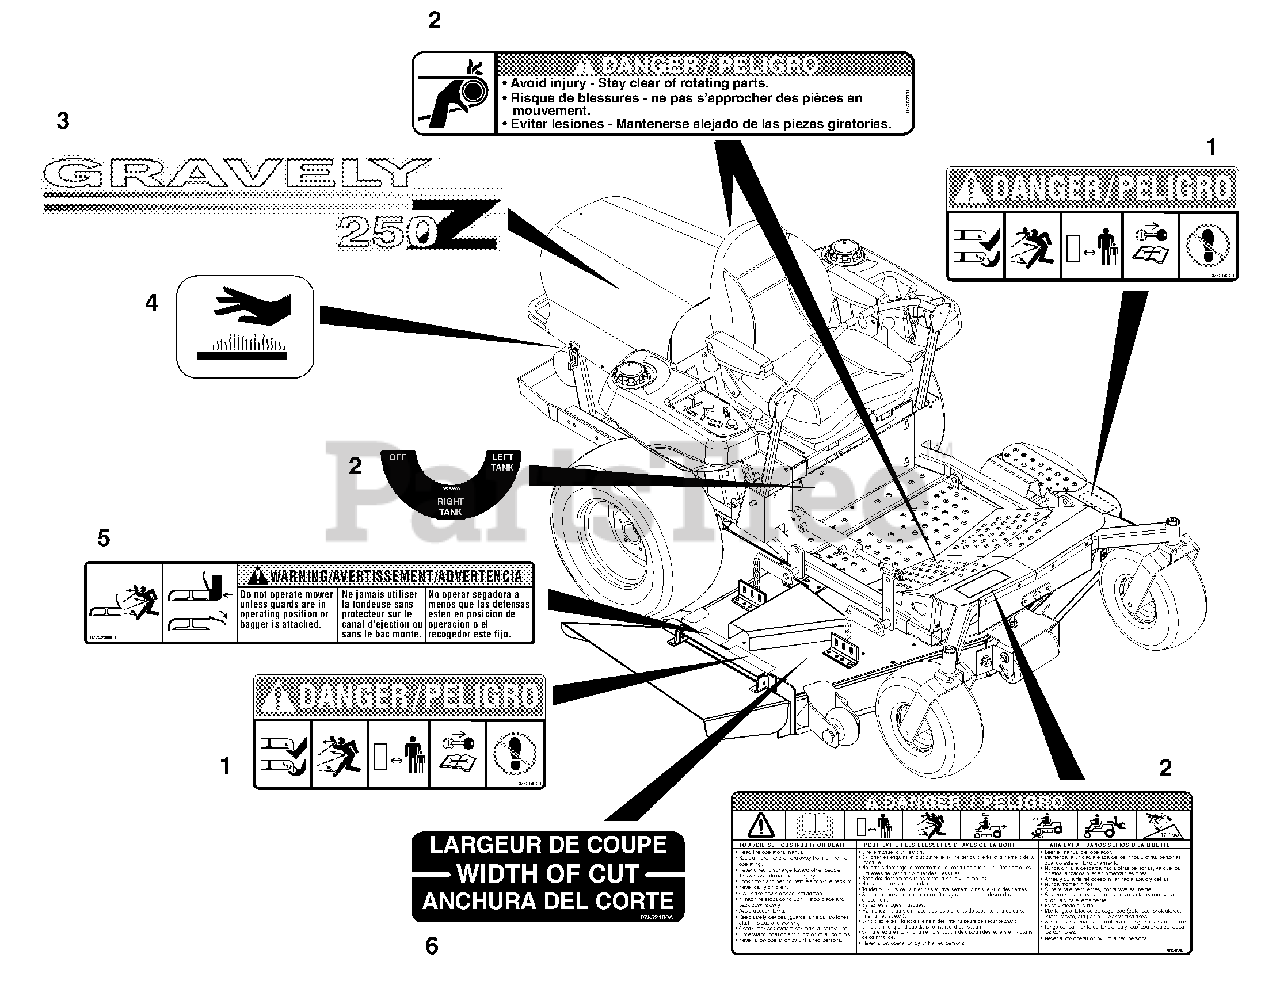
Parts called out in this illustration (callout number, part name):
1	Decal, Mower Pan Head Danger
2	Set, Decal-Common Danger/Fuel
3	Decal, PM-250Z Hood (034, 035)
3	Decal, PM-260Z Hood (020, 029, 033)
3	Decal, PM-272Z Hood (030, 032)
4	Decal-Hot Surface
5	Decal, Warning
6	Decal, Width of Cut
